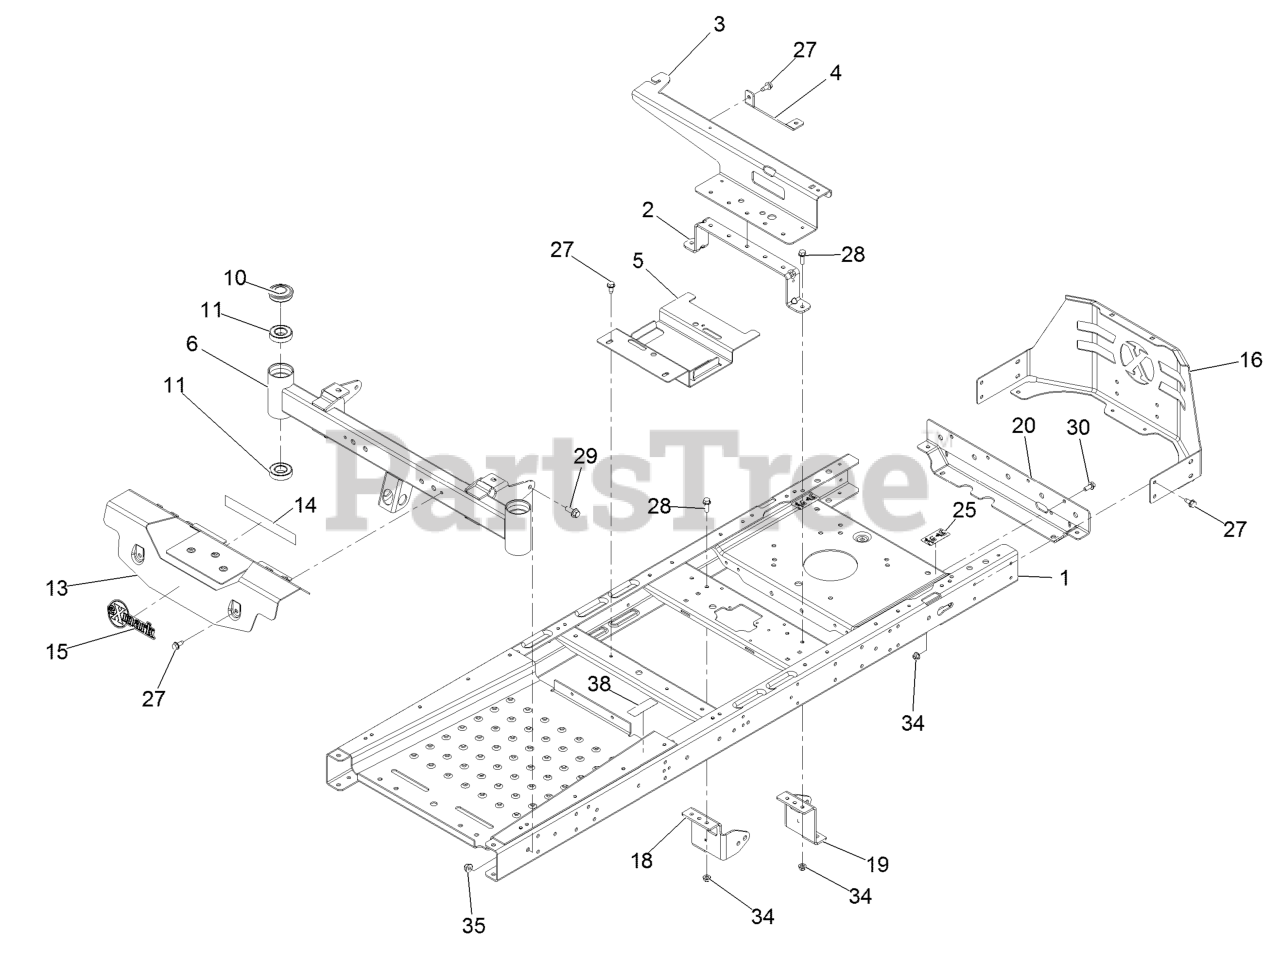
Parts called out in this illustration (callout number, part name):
1	Frame ASM
2	Brace-Seat, Rear (Narrow)
3	Support-Pod [black]
4	Support-Tank, Rear
5	Bracket-Battery
6	Axle-Front, Narrow
10	Cap-Grease
11	Bearing-Ball
13	Footrest ASM
14	Decal-Warning
15	Decal-Exmark Logo
16	Guard-Engine, Narrow [black]
18	Mount-Hydro, Front (Right)
19	Mount-Hydro, Front (Left)
20	Crossmember-Rear, Narrow
25	Decal-Bypass
27	Screw-HWH 5/16-18 X 3/ Tf
28	Screw-HH Flg 5/16-18 X 1
29	Screw HHF 3/8-16 X 1
30	Screw-HH Flg 5/16-18 X 3/4
34	Nut-Nyloc 5/16-18 Flg
35	Nut-Nyloc 3/8-16 Flg
38	Decal-Brake, Parking
